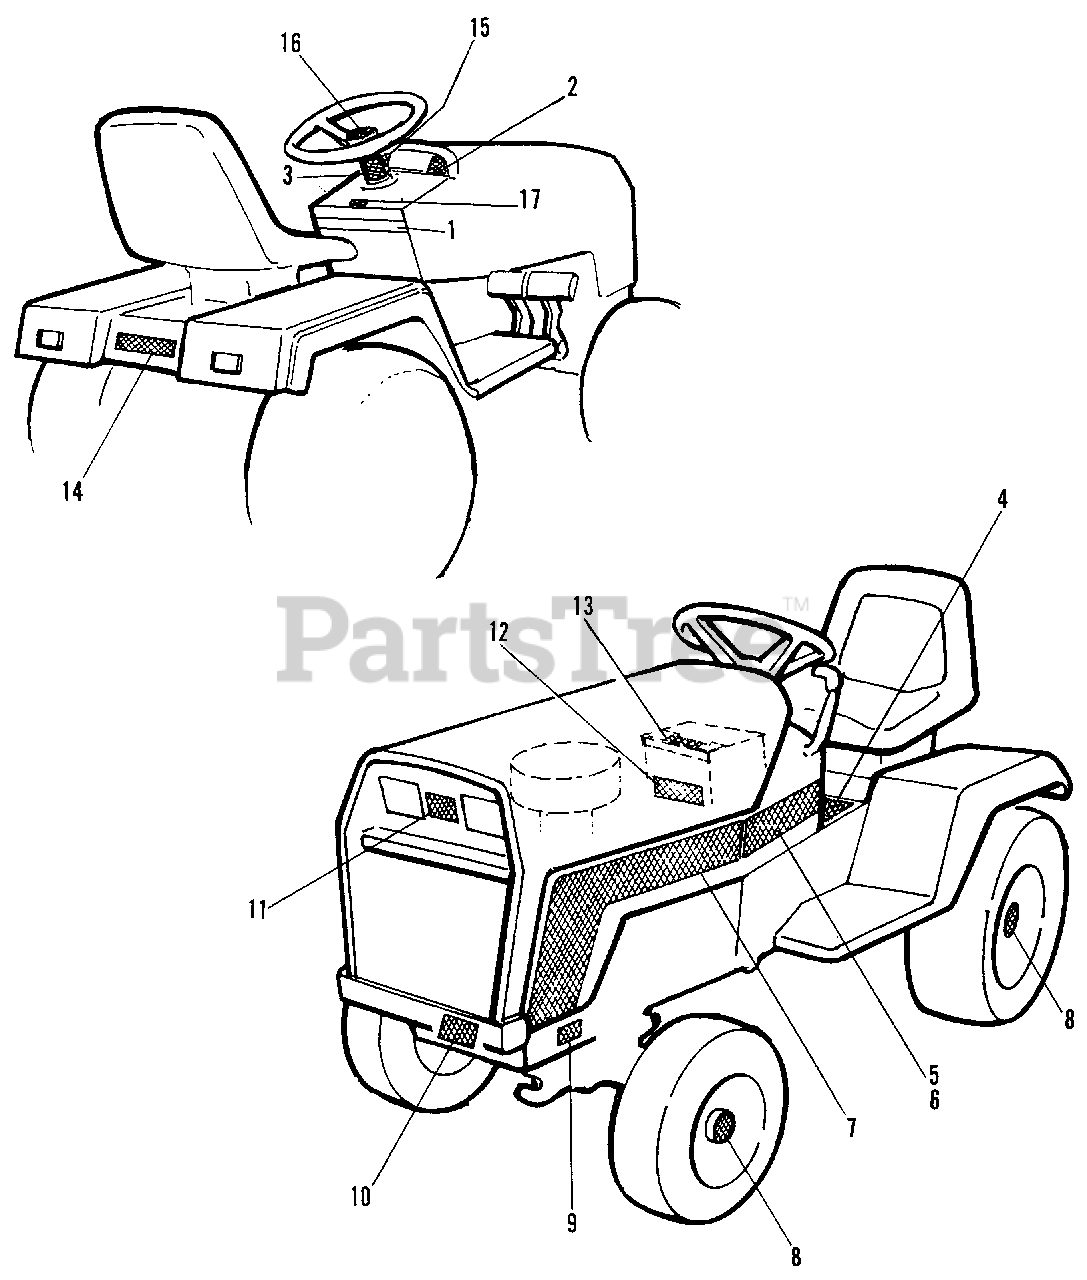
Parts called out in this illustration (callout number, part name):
1	DECAL, Panel, Rear Dash (Choke, Ignition, etc.)
2	DECAL, Indicator, R.H. (Front PTO, Seat)
3	DECAL, Steering Wheel Shaft, 2" x 5" (1691018 only)
4	DECAL, Tunnel Cover (1691017, 1691250, 1691357, 1691380, 1691528)
4	DECAL, Tunnel Cover (1691018)
4	DECAL, Tunnel Cover (1691381, 1691710 only)
5	DECAL, Side Panel, L.H. (1691017, 1691380, 1691528 only)
5	DECAL, Side Panel, L.H. (1691018, 1691381, 1691710 only)
5	DECAL, Side Panel, L.H. (1691250 only)
5	DECAL, Side Panel, L.H. (1691357 only)
6	DECAL, Side Panel, R.H. (1691017, 1691380, 1691528 only)
6	DECAL, Side Panel, R.H. (1691018, 1691381, 1691710 only)
6	DECAL, Side Panel, R.H . (1691250 only)
6	DECAL, Side Panel, R.H. (1691357 only)
7	DECAL, Hood, L.H.
7	DECAL, Hood, R.H.
8	DECAL, Hub Cap
9	I.D. PLATE
10	DECAL, Warning, Front PTO Shield
11	DECAL, Grille Logo
12	DECAL, Battery
13	DECAL, Warning (Disconnect Elect. Ground, etc.)
14	DECAL, Rear Logo
15	DECAL, Indicator, L.H. (all models except 1691250, 1691357)
15	DECAL, Indicator, L.H. (1691250, 1691357 only)
16	DECAL, Steering Wheel Cap
17	DECAL, Rear PTO (1691710)
